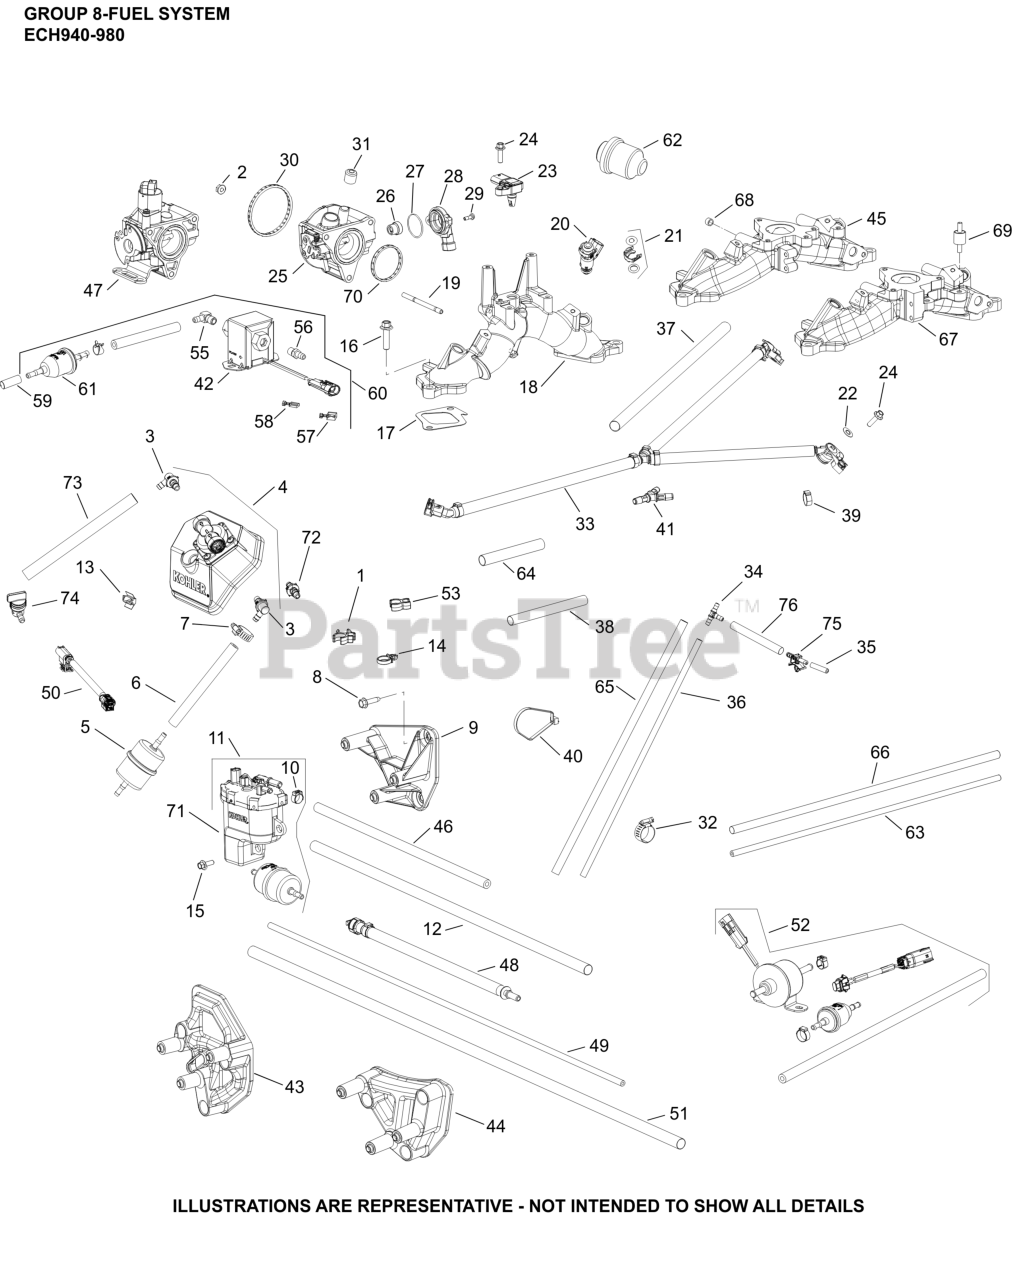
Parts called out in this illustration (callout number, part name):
1	RETAINER, HOSE
3	KIT, 90 DEG. FITTING
4	KIT, FUEL PUMP
5	FILTER, FUEL
6	HOSE,LW PERM.FUEL 24.00"-USE 25 111 81-S
7	CLAMP, HOSE (KM)-USE 25 237 31-S
8	SCREW, THREAD FORMING
9	BAFFLE, FUEL PUMP MODULE (HORZ)
10	CLAMP, OETIKER
12	SLEEVE, ANTI ABRASION
13	CLIP, O2 SENSOR
14	CLIP, FUEL LINE
15	SCREW, FLG M6X1.0X16
17	GASKET, INTAKE MANIFOLD
18	MANIFOLD, INTAKE HORIZONTAL (EFI)
19	STUD,M6X1.0X84
20	INJECTOR, FUEL
21	KIT, FUEL INJECTOR O-RING
22	CLIP, RETAINER
23	SENSOR, T-MAP
24	SCREW, FLG M6x1.0x20
25	BODY, THROTTLE ASM (34)
26	MAGNET ASSEMBLY, TPS
27	O-RING, TPS SENSOR
28	SENSOR, THROTTLE POSITION
30	O-RING (HDAC SEAL-EFI)
31	CAP, MASKING
33	RAIL ASSEMBLY, FUEL (HORZ)
34	TEE CONNECTOR
35	CAP, MASKING
36	HOSE, EVAPORATIVE
37	SLEEVE, ANTI ABRASION
38	SLEEVE, ANTI ABRASION -USE 25 431 12-S
39	CLAMP, HOSE
46	HOSE, FUEL (LOW-PREMEATION, 1/4" ID)
70	O-RING, THROTTLE BODY
71	KIT, FUEL PUMP MODULE
